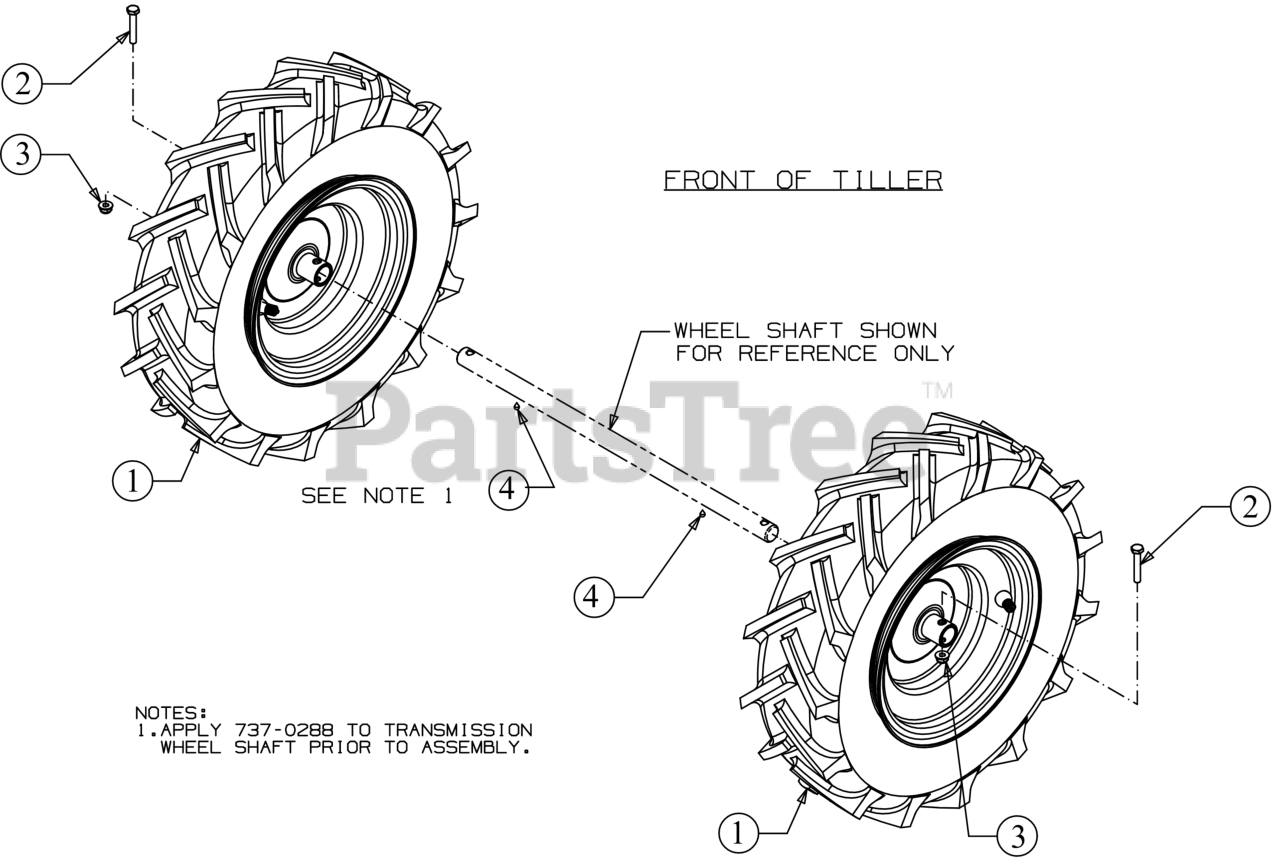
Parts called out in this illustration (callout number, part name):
1	WHEEL ASSEMBLY (16 X 4.6-8) (CRAFTSMAN GREY)
1	RIM ASSEMBLY (8 X 3.75)
1	TUBELESS VALVE
1	TIRE 16.25 X 4.5-8
2	SCREW 1/4-20 X 1.50 GR8
3	FLANGE LOCK NUT
4	GREASE
